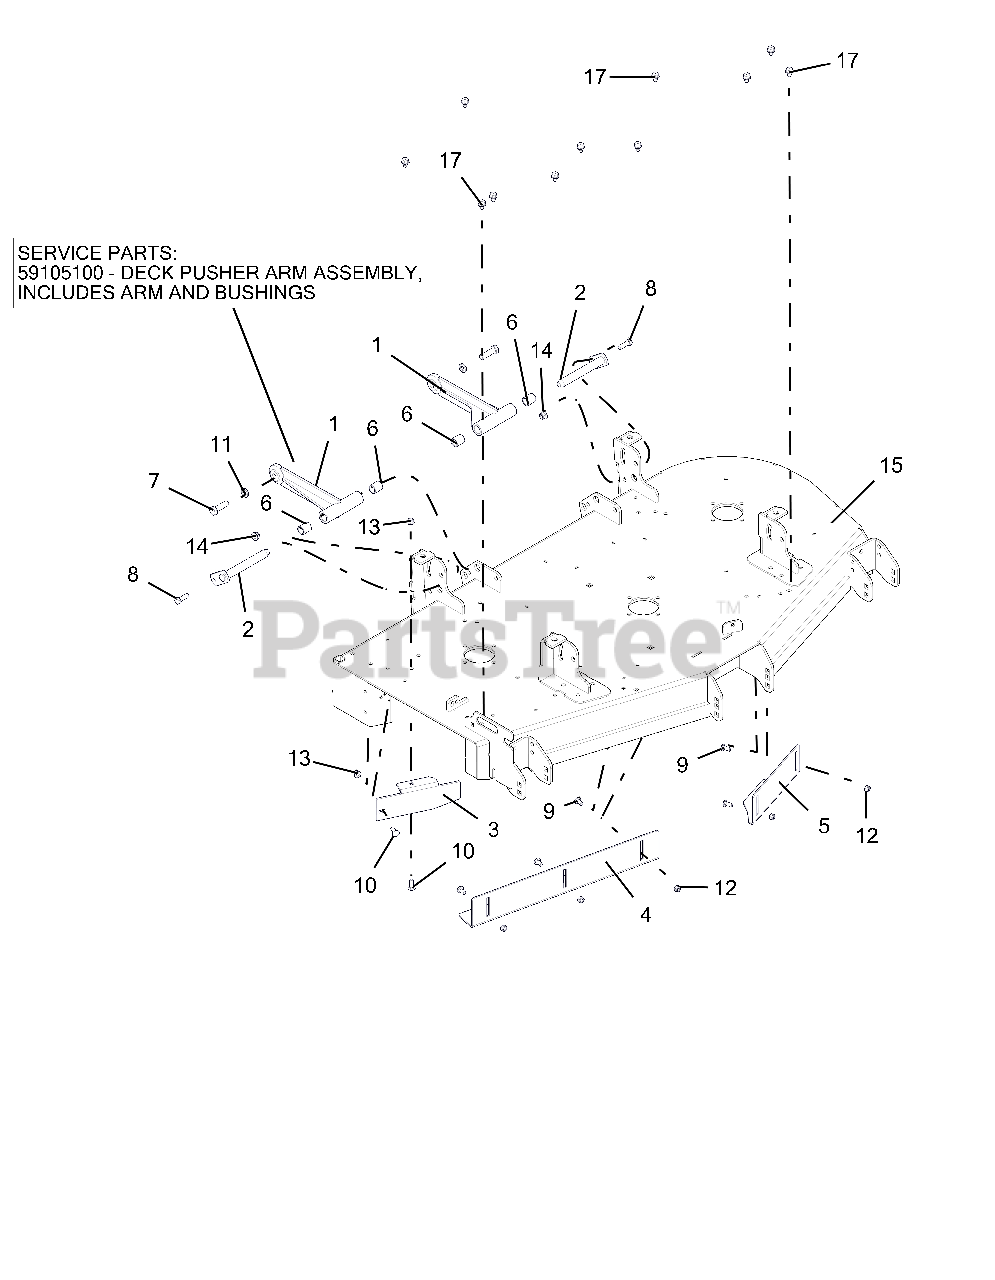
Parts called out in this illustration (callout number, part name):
1	WLDMT, DECK PUSHER ARM
1	DECK PUSHER ARM ASSEMBLY
2	WLDMT, MOWER MTG. PIN
3	BAFFLE, 52" DISCHARGE-RED
4	BAFFLE, 52" RH VACUUM-BLACK
5	BAFFLE, 52" LH VACUUM-BLACK
6	BRG, .750 X .875 X 1.000
7	BLT-HEX .50-13X1.75 GR5 YWZC EP80
8	BLT-HEX .38-16X1.25 GR5 YWZC
9	BLT-RDHDSQNK .31-18X.75 G5 YWZC
10	BLT-RDHDSQSHNK .31-18X1.00 G5 Y
11	WSHR-LK .50X.125 REG YWZC
12	NUT-LK-NYL .312-18 YWZC
13	NUT-LK-NYL-FLG .31-18 YWZC
14	NUT-LK-NYL-FLG .38-16 YWZC
15	KIT, PT152 MOWER DECK W/SAFETY DECALS-RED
16	SCR-TAP .38-16X.50 HWH TR YWZ
17	SCR-TAP .38-16X.50 HWH TR YWZ
